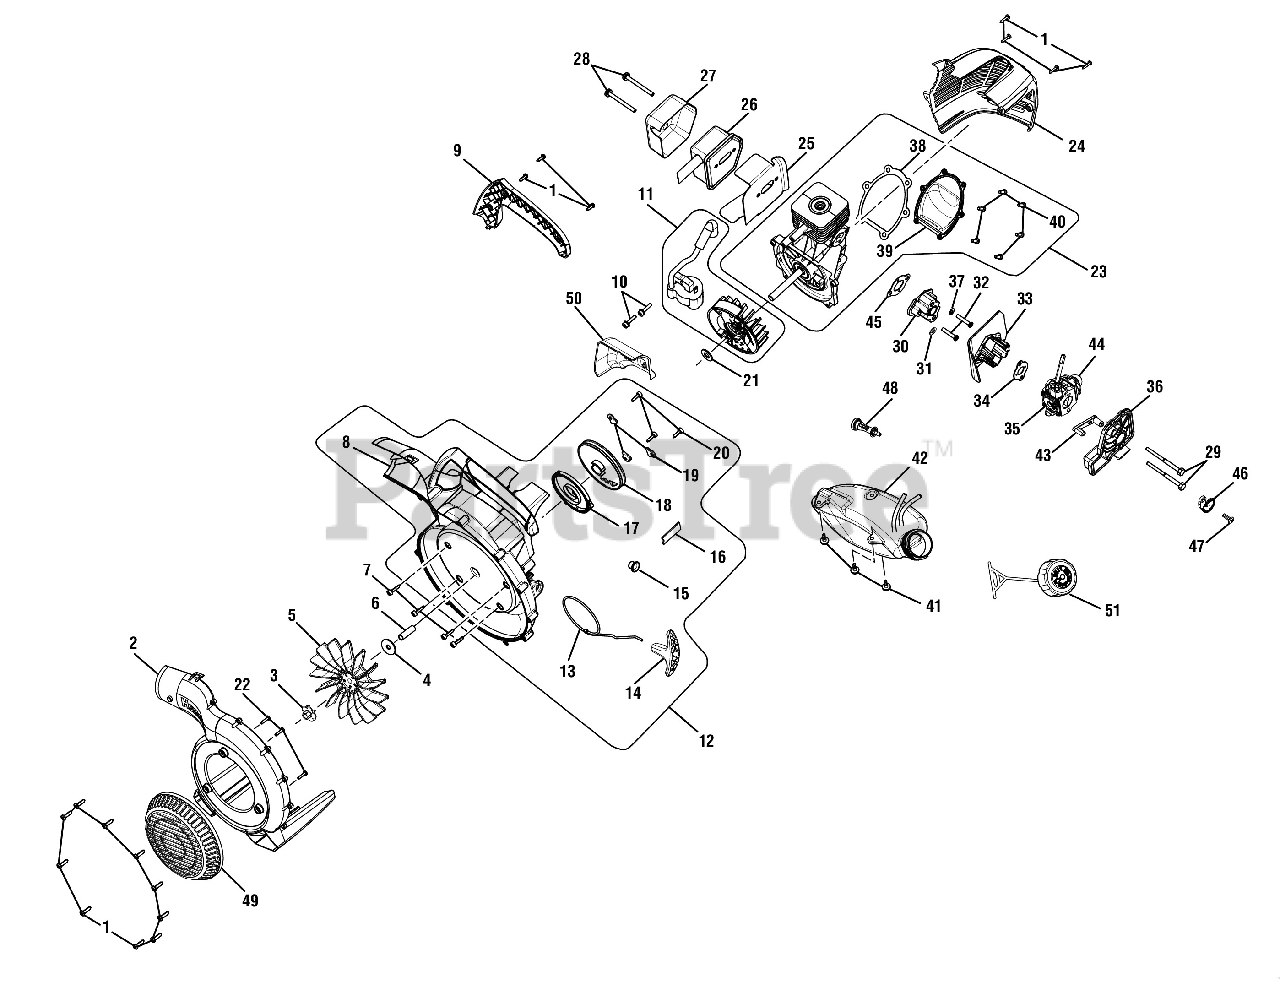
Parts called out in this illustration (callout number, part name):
1	Screw (M4 x 18 mm, T20 Torx Pan Hd. S.T.)
2	Outer Volute w/Label
3	Lock Nut (3/8 in.)
4	Washer (ID9.8 x OD34.27 x 2.28t)
7	Screw w/Washer (M4 x 16 mm, T25 Torx Truss Hd.)
8	Inner Volute w/Eyelet and Label
9	Handle Cover
10	Screw w/Washer (M4 x 19 mm, T20 Torx Pan Hd. S.T.)
11	Ignition Module and Flywheel Kit
12	Lower Housing w/Starter and Label Assembly
13	Starter Rope (42 in.)
14	Pulley Handle
17	Spring & Container Assembly
18	Starter Pulley
19	Pulley Retainer
20	Screw (M4 x 14 mm, T20 Torx Truss Hd T.F.)
21	Washer (ID9.70 x OD20 x 1.59t)
22	Screws (10-14 x 3/4 in., T25 Torx Pan Hd. T.F.)
23	Short Block Assembly
24	Engine Cover w/Label
25	Muffler Gasket
26	Muffler Assembly
27	Muffler Heat Shield
28	Screw w/Washers (10-24 x 2-1/8 in., T25 Torx Truss Hd.)
29	Bolt (M5 x 48 mm, T20 Torx hd.)
31	Washer (ID5 x OD10.9 x 0.5t)
32	Screw (M5 x 25 mm, T20 Torx Hd.)
34	Heat Dam Gasket
35	Carburetor
36	Air Box Base
38	Crankcase Cover Gasket
39	Crankcase Cover
40	Screw (M4 x 12 mm, T20 Torx Hd.)
41	Shoulder Screw w/Washer (M4 x 14 mm, T25 Torx Truss Hd.)
42	Fuel Tank Assembly (Inc. Fuel Lines)
43	Choke Lever
44	Primer Bulb (Ruixing)
45	Intake Gasket
46	Choke Cover
47	Screw (M4 x 12 mm, Slotted Recessed Pan Hd.)
48	Fuel Filter
49	Blower Door
50	Baffle Plate
51	Fuel Cap Assembly (Inc. Tether)
